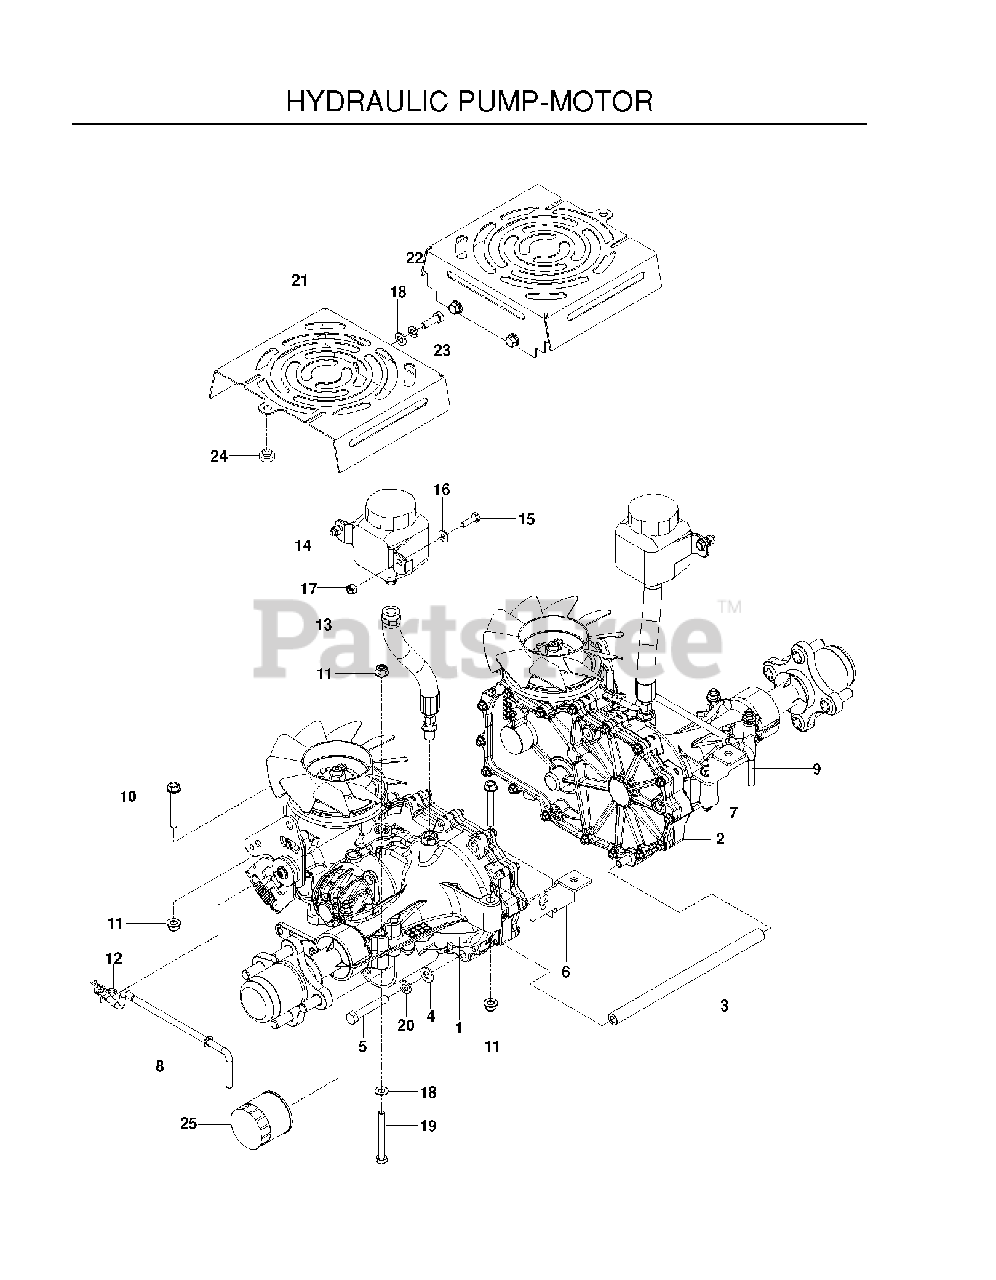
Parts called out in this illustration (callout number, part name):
1	HG_TRANS, ZT-3400, LT
2	HG_TRANS, ZT-3400, RT
3	TUBE, SPACER, 3400
4	WASHER 3/8 SAE FLAT
5	HCS 3/8-16X2-1/4 LOC PATCH GR8
6	BRACKET.TRANS.LT.BLACK
7	BRACKET, TRANS, RT BLACK
8	LINKAGE, LEFT BYPASS
9	LINKAGE, RIGHT BYPASS
10	HHFS 5/16-18 X 2.25 GD 5
11	5/16-18 NYLOC FLANGE NUT
12	HAIRPIN #2
13	HOSE ASSY, EXPANSION
14	TANK.EXPANSION.350ML 71328
15	HCS 1/4-20X7/8 GR5
16	WASHER 1/4 SAE
17	RP_NUT 1/4-20 NYLOC
18	FLAT WASHER 5/16 SAE
19	HCS 5/16C X 2-3/4
20	SLW 3/8 STD
21	SHIELD, FAN, BLK
22	WASHER 5/16 LOCK
23	HCS 5/16C X 1
24	GROMMET, BUMPER
25	HG_FILTER, ZT4800 52114
